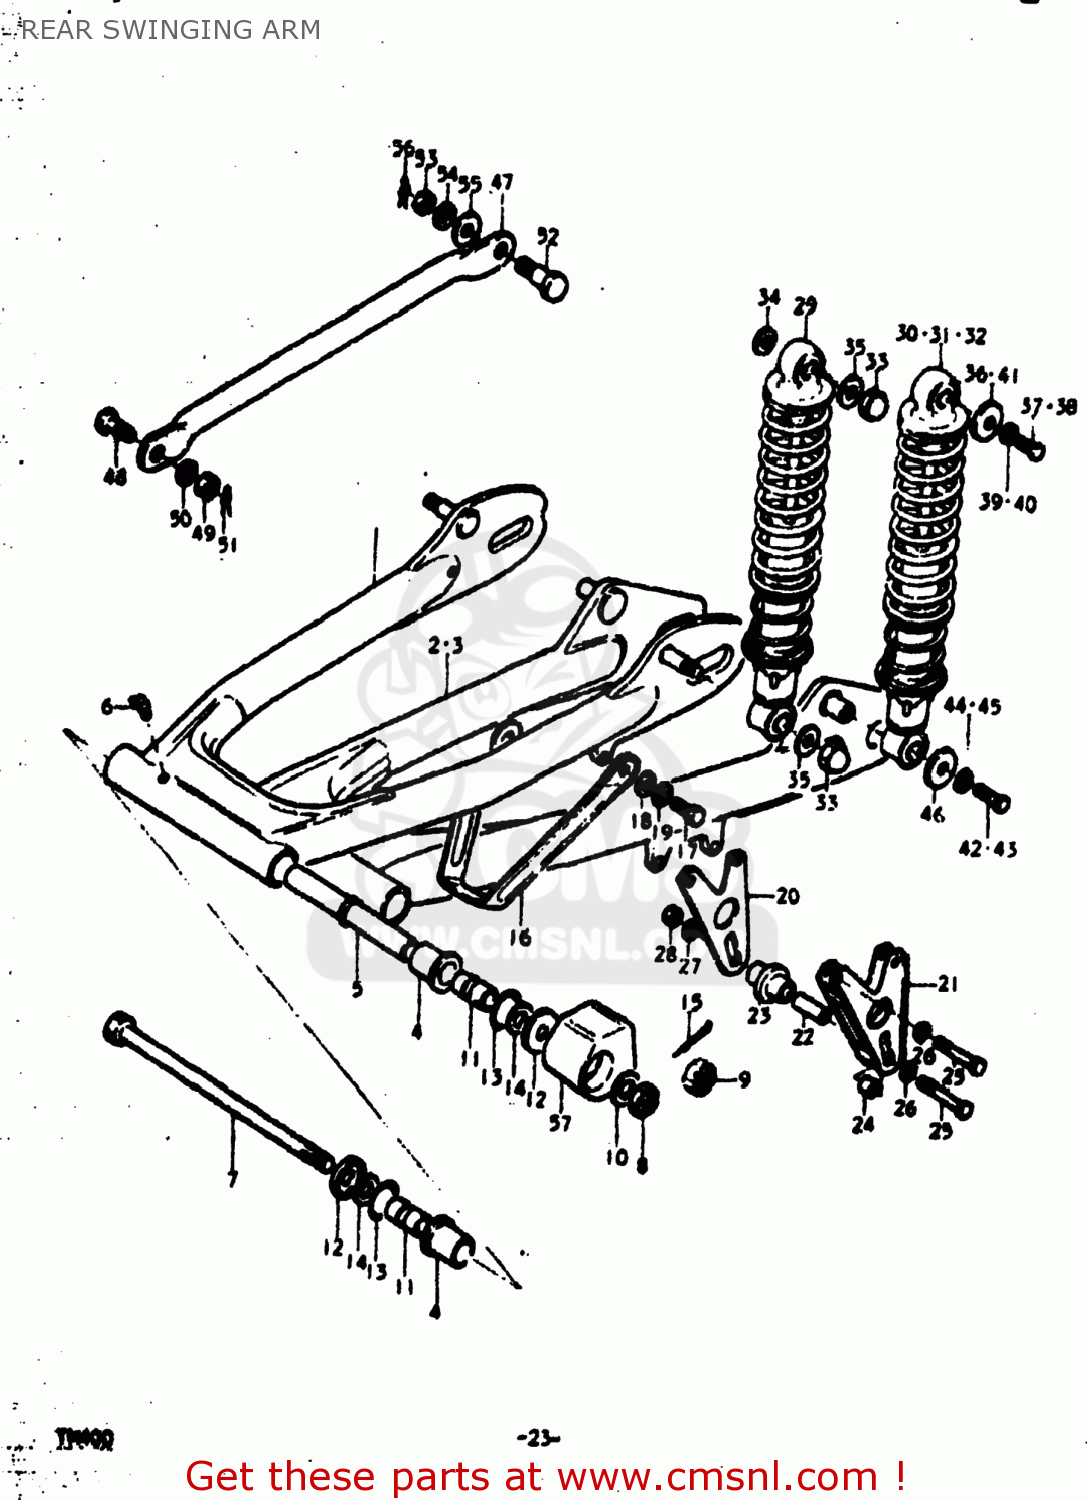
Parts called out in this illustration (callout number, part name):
1	SWING ARM ASSEMBLY,REAR
2	SWING ARM ASSEMBLY,REAR
3	SWING ARM ASSEMBLY,REAR
4	BUSHING
5	SPACER,SWING ARM,CENTER
6	NIPPLE,GREASE
7	SHAFT,REAR SWING ARM
8	NUT
9	NUT
10	WASHER
11	SPACER,REAR SWING ARM
12	COVER
13	O RING(D:2,ID:24.5)
14	WASHER(12.5X24X2.3)
15	COTTER PIN
16	GUIDE,CHAIN
17	BOLT
18	WASHER 6MM
19	LOCK WASHER
21	TENSIONER,CHAIN
22	SPACER
23	ROLLER,CHAIN GUIDE
24	SPACER(6.5X12X6.9)
25	BOLT
26	LOCK WASHER
27	WASHER
28	SCREW
29	ABSORBER ASSEMBLY,REAR SHOCK
30	ABSORBER ASSEMBLY,REAR SHOCK
31	ABSORBER ASSEMBLY,REAR SHOCK
32	ABSORBER ASSEMBLY,REAR SHOCK
33	NUT
34	WASHER
35	WASHER
36	WASHER,LOCK
37	BOLT
38	BOLT 12X50
39	LOCK WASHER
40	WASHER
41	WASHER (6.5X29X1.6)
42	BOLT
43	BOLT(12X33)
44	LOCK WASHER
45	WASHER
46	WASHER (6.5X29X1.6)
47	TORQUE LINK,REAR
48	BOLT(8X22.5)
49	NUT
50	LOCK WASHER
51	CLIP
52	BOLT
53	NUT
54	LOCK WASHER
55	WASHER (12.5X24X1.6)
56	CLIP
57	BUFFER,CHAIN TOUCH DEFLECTOR
